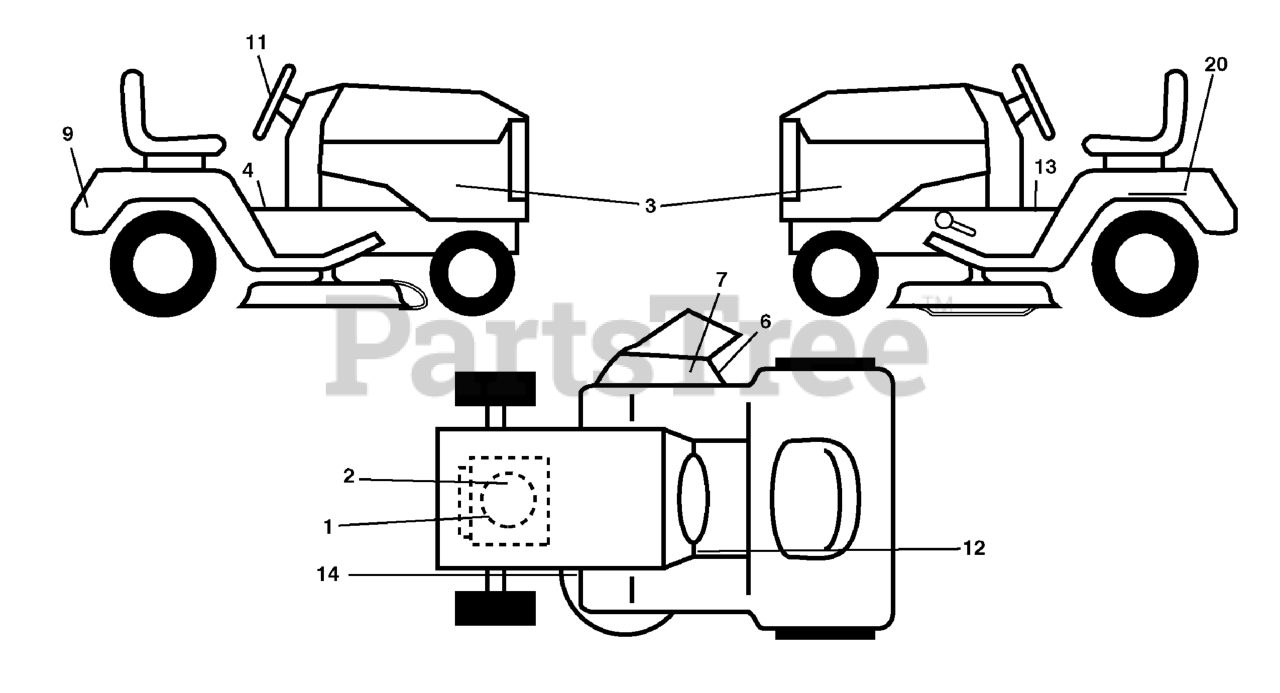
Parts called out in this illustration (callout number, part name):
1	Decal Warning
2	Decal Eng. H.P.
3	Decal SDPNL
4	Decal Warning
6	Decal Warning, Keep Hand Away
7	Decal Cutfinger CE
9	Decal Fender Logo
11	Decal Ins Strg Whl
12	Decal Brake Clutch
13	Decal Saddle Brake Park
14	Decal V-Belt Schematic
20	Decal Bat Dan/Psn
